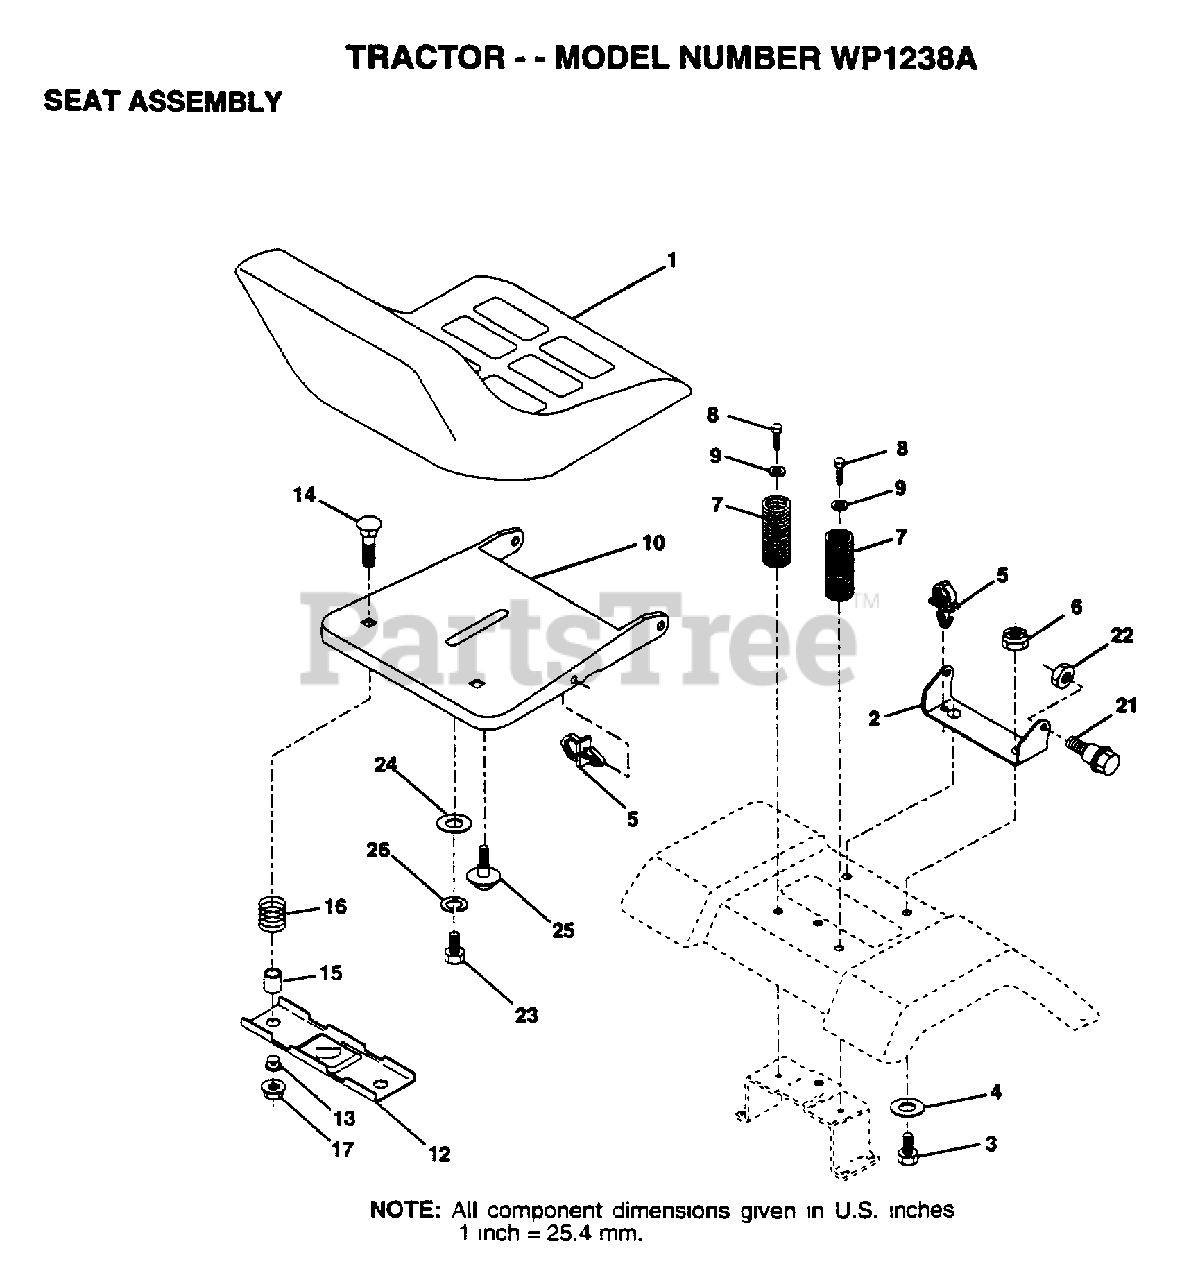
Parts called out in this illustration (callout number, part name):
2	BRACKET PVT SEAT
3	BOLT
4	WASHER PM
5	CLIP.PUSH-IN.HING
6	NUT
7	SPRING COMPRESSIO
8	SCREW GTV
9	WASHER
12	BRKT SWITCH
13	BUSHING
15	SPLIT SPACER
16	SPRING
21	BOLT.SHLD.5/16-18
22	NUT
23	BOLT
24	WASHER
25	"BOLT,SHOULDER"
26	LOCKWASHER
